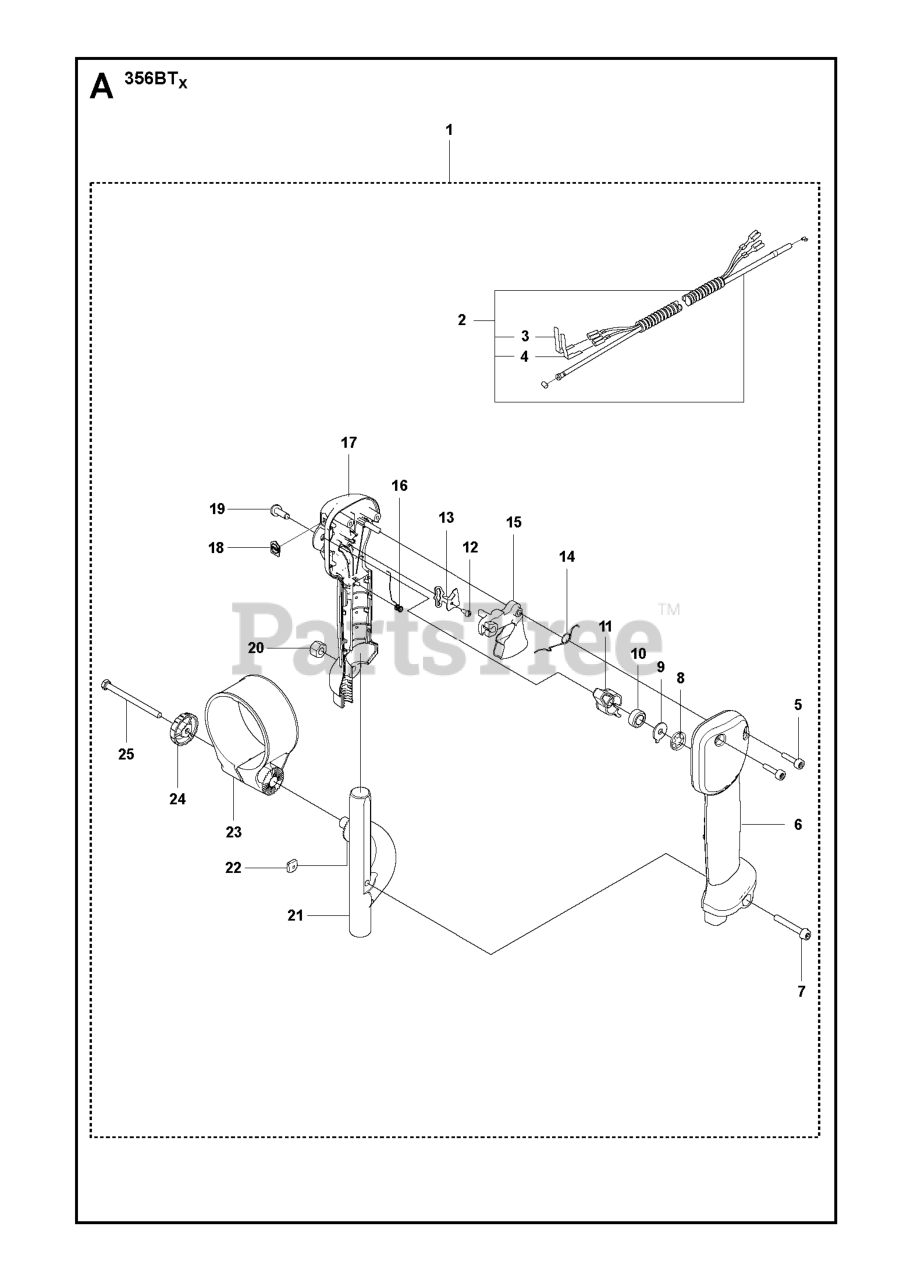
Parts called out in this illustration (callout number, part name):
1	HANDLE ASSY
2	WIRING ASSY
3	CONTACT SPRING
4	CONTACT SPRING
5	SCREW
6	HANDLE HALF (R)
10	SPRING RUBBER
11	LEVER STOP
15	TRIGGER 848L5W34C0
17	HANDLE HALF (L)
19	SHAFT PIVOT
21	HOLDER, HANDLE
